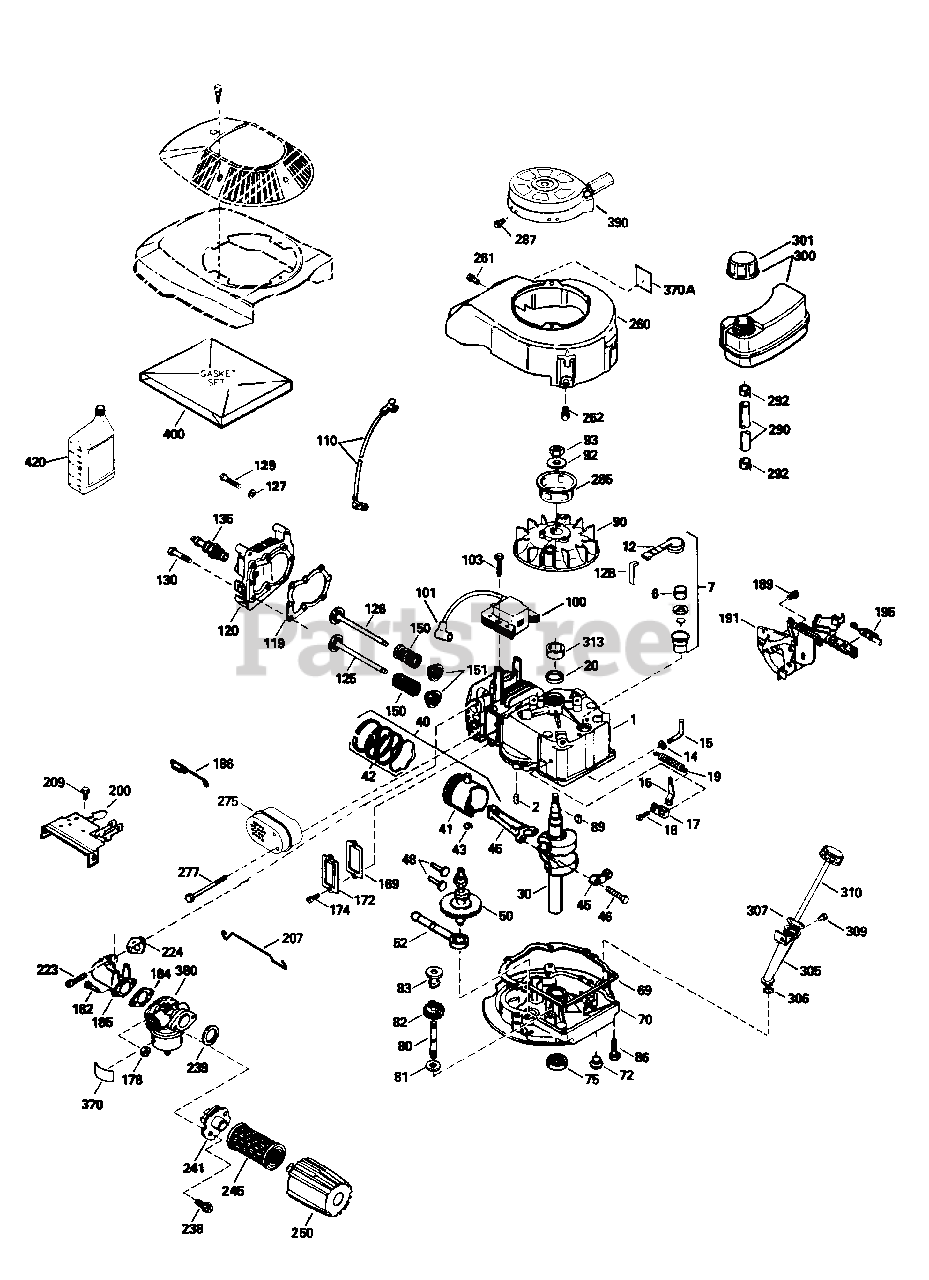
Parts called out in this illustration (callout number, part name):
1	Cylinder (Incl. 2,7,20 & 125)
2	Dowel Pin
6	Breather Element
7	Breather Body Ass'y (Incl. 6 & 12)
12	Breather Cover & Tube (Incl. 12B)
12B	Breather Tube Elbow
15	Governor Rod
16	Governor Lever
17	Governor Lever Clamp
19	Extension Spring
20	Oil Seal
30	Crankshaft
40	Piston, Pin & Ring Set (Std.)
40	Piston, Pin & Ring Set (.010" OS)
40	Piston, Pin & Ring Set (.020" OS)
41	Piston & Pin Ass'y. (Std.)(Incl. 43)
41	Piston & Pin Ass'y(.010" OS)(Incl. 43)
41	Piston & Pin Ass'y(.020" OS)(Incl. 43)
42	Ring Set (Std.)
42	Ring Set (.010" OS)
42	Ring Set (.020" OS)
43	Piston Pin Retaining Ring
45	Connecting Rod (Incl. 46)
46	Connecting Rod Bolt
48	Valve Lifter
50	Camshaft (MCR)
52	Oil Pump Ass'y.
69	Mounting Flange Gasket
70	Mounting Flange (Incl. 72 thru 83)
72	Oil Drain Plug
75	Oil Seal
80	Governor Shaft
82	Governor Gear Ass'y (Incl. 81)
83	Governor Spool
89	Flywheel Key
90	Flywheel
92	Belleville Washer
93	Flywheel Nut
100	Solid State Ignition
101	Spark Plug Cover
103	Screw, Torx T-15
110	Ground Wire
119	Cylinder Head Gasket
120	Cylinder Head
125	Exhaust Valve (Std.)(Incl. 151)
125	Exhaust Valve (1 /32" OS)(Incl.151)
126	Intake Valve (Std .)(Incl.151)
126	IntakeValve (1/32" OS)(Incl.151)
135	Resistor Spark Plug (RJ19LM)
150	Valve Spring
151	Valve Spring Cap
169	Valve Cover Gasket
172	Valve Cover
178	Nut & Lock Washer
182	Screw
184	Carburetor To Intake Pipe Gasket
185	Intake Pipe (Incl.224)
186	Governor Link
191	S.E. Brake Bracket (Incl.195)
195	Terminal
200	Control Bracket
207	Throttle Link
224	Intake Pipe Gasket
238	Air Cleaner Gasket
241	Air Cleaner Collar
245	Air Cleaner Filter
250	Air Cleaner Cover
260	Blower Housing
275	Muffler (Incl.277)
285	Starter Cup
290	Fuel Line
292	Fuel Line Clamp
300	Fuel Tank (Incl. 292 & 301)
301	Fuel Cap
305	Oil Fill Tube
306	"O"-Ring
307	"O"-Ring
310	Dipstick
370	Primer Decal
370A	Lubrication Decal
380	Carburetor (Incl. 184)
390	Rewind Starter (NOTE:This engine could have been built with 590637 starter. Refer to the design of the air intake louvers for part identification . Individual starter parts do not interchange.)
400	Gasket Set (Incl. Items Marked PK in Notes) Incl. part #'s: 26756 (1), 27234A (1), 33735 (1), 34265(1), 34338 (1), 34690A (1), 35261 (1) 36477 (1)
420	SAE 30 4-Cycle Engine Oil (Quart)
